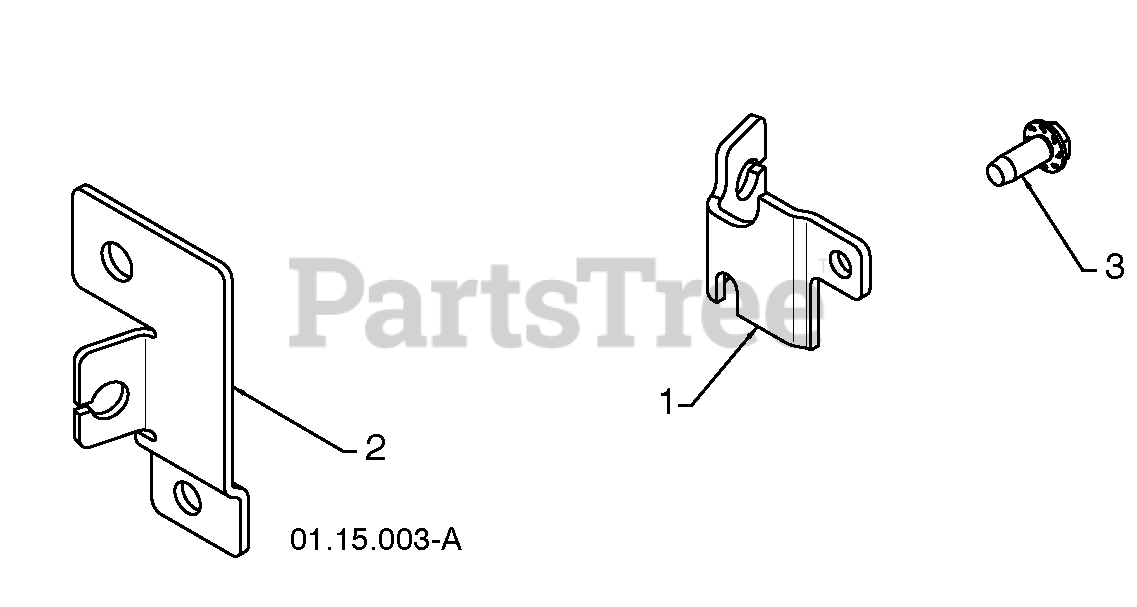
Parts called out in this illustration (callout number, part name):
1	CABLE BRACKET LH
2	CABLE BRACKET RH
3	SCREW 1/4-20 X .625
